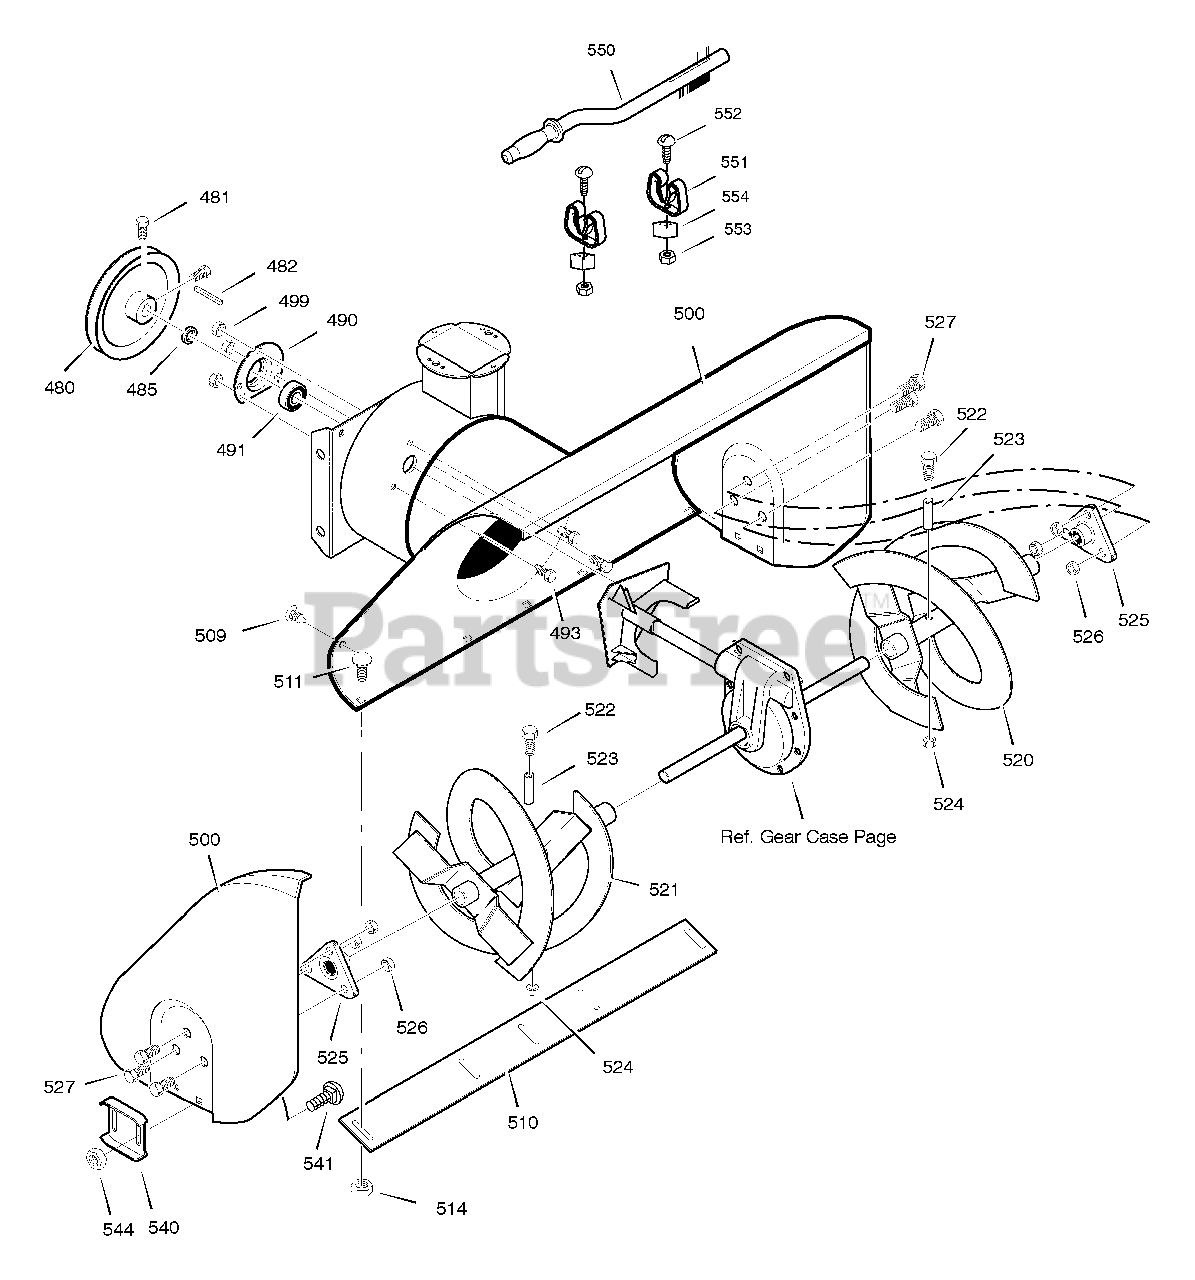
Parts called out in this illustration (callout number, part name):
480	PULLEY, 4L 8.4 X .67 HYBRID
481	SCREW, 5/16-18 x 0.62
482	KEY, SQUARE 3/16 X 3/4
485	SPACER, FRICTION PULLEY
490	RETAINER, BALL BRNG
491	BEARING, BALL
493	BOLT, HEX 5/16-18X .50
499	NUT, 5/16-18 HEXWDFLLK
500	HOUSING, ASSY
509	PLUG, CHRISTMAS TREE
510	BLADE, SCRAPER
511	BOLT, 5/16-18X.75
514	NUT, 5/16-18
520	AUGER, ASSY, LH
521	AUGER, ASSY, RH
522	SCREW, 1/4-20X1.75
523	SPACER, SLEEVE
524	NUT, 1/4-20
525	BEARING,FLANGE
526	NUT, 5/16-18
527	SCREW, 5/16-18 x 0.75
540	SKID, HEIGHT ADJUST
541	BOLT, 5/16-18 X .75
544	NUT, 5/16-18
550	BRUSH, CLEANOUT
551	CLIP, RETAINER
552	SCREW
553	NUT
